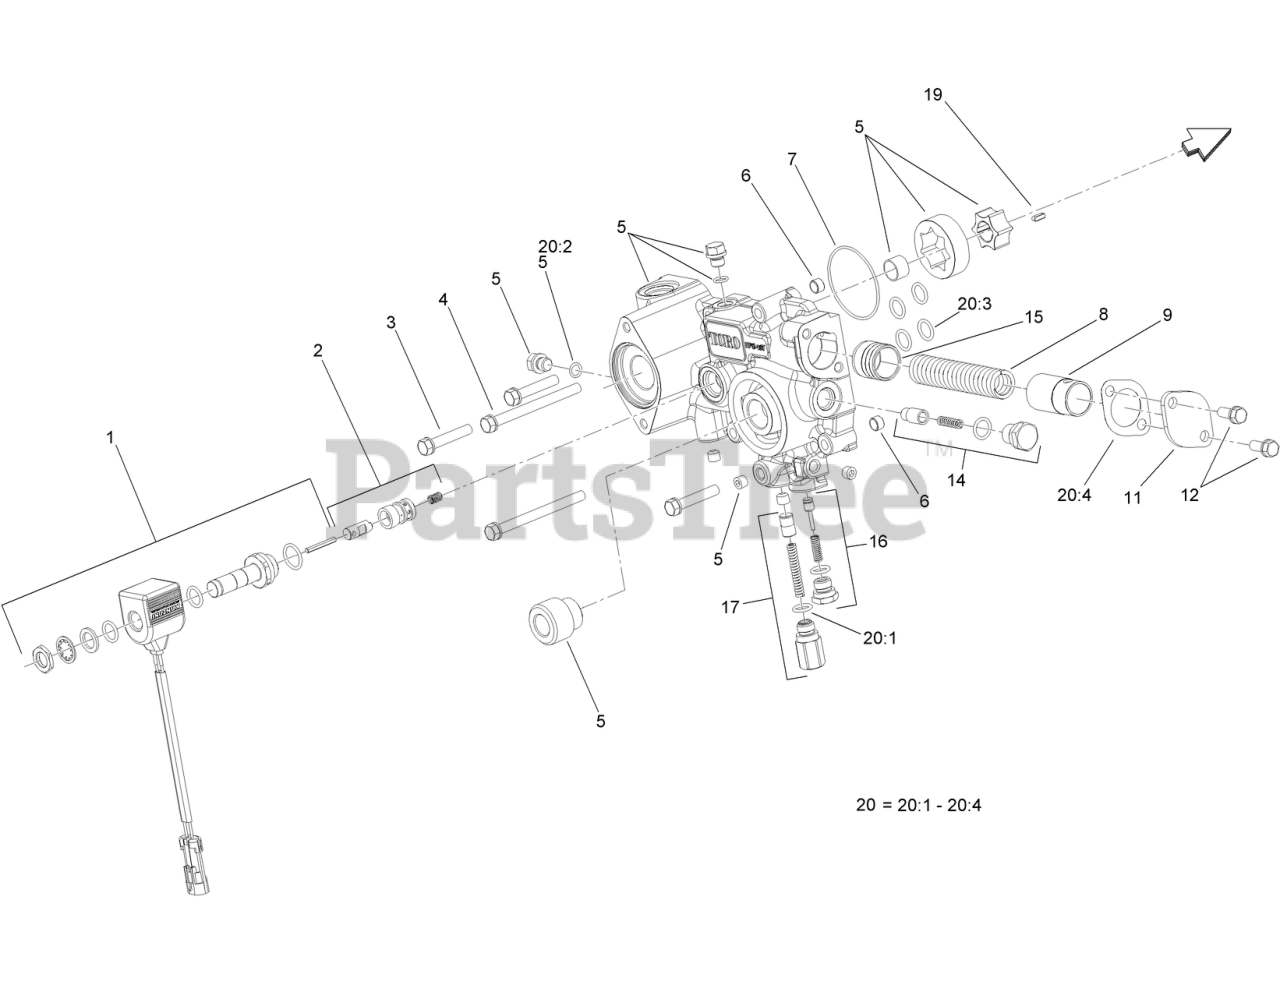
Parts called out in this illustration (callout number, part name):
1	SOLENOID ASM
2	SOLENOID VALVE ASM
5	PUMP BODY ASM
7	O-RING
8	SPRING
9	COLLAR
12	BOLT AND WASHER ASM
14	FILTER BYPASS VALVE ASM
15	PISTON
16	CHARGE RELIEF VALVE ASM
17	PRESSURE VALVE ASM
20	CHARGE PUMP SEAL KIT
20:1	O-RING
20:2	O RING-PLUG
20:4	GASKET
